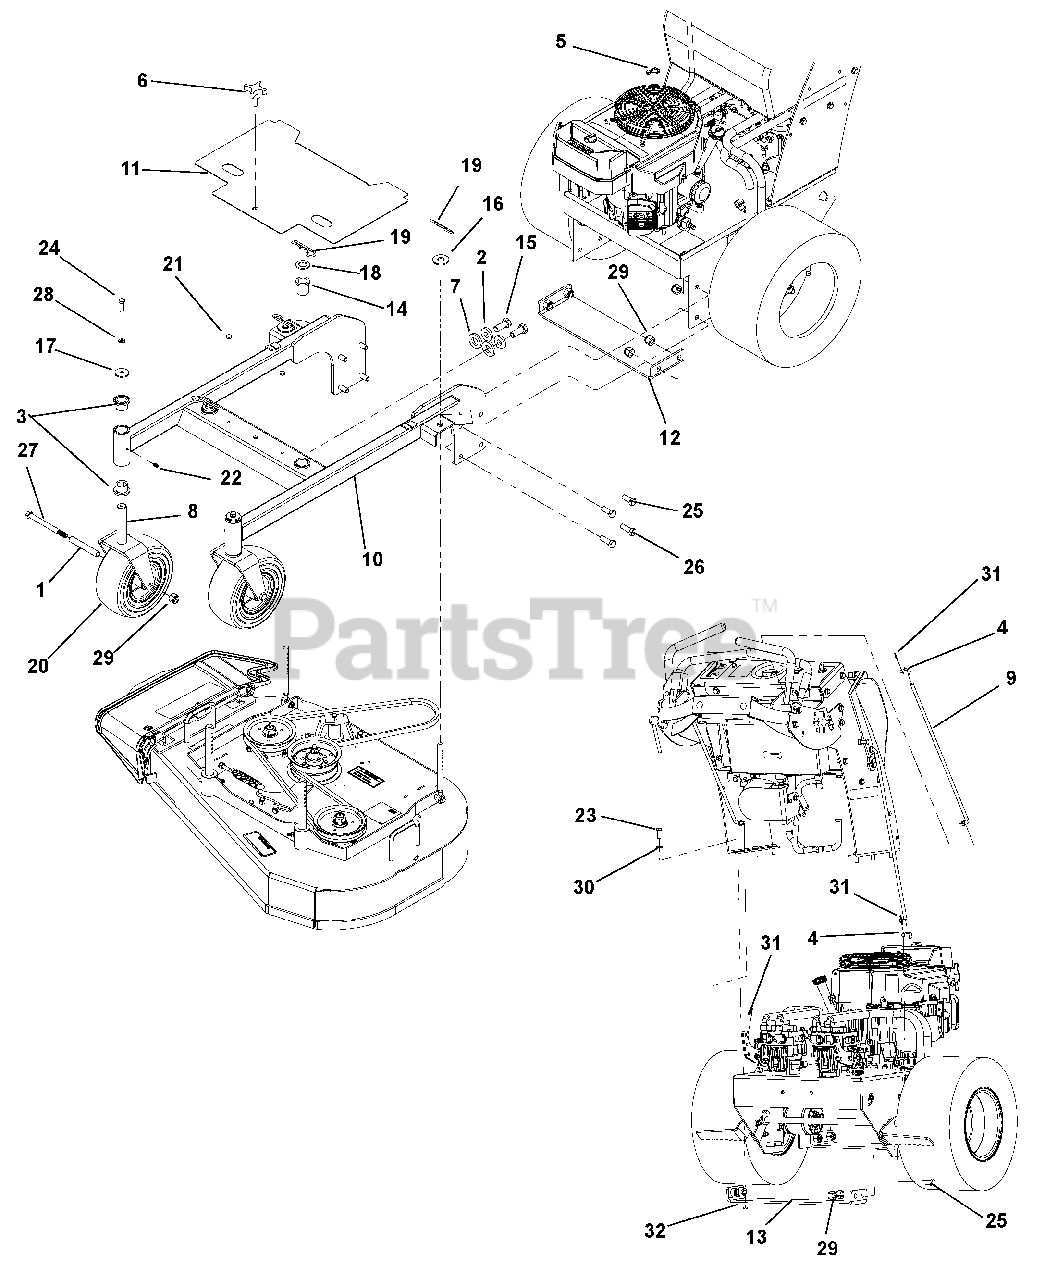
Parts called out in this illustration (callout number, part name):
1	TUBE, CASTER AXLE
2	WASHER, BLADE
3	BRG, FLG 1.00 X 1.25 X 1.00
4	SWIVEL, 3/8-24
5	CABLE TIE, .15 X 8.50
6	KNOB, 3/8 X 1.25 - 4 PRONG
7	WASHER, .905 X 1.750 X .250
8	WLDT, FRONT WHEEL FLOAT WALK
9	ROD, DRIVE CONTROL FW
10	WLDT, FRAME 36" FLWLK
11	SHIELD, BELT 36" FLOAT WALK
12	PLATE, ENGINE BED FRONT 36
13	PLATE, ENGINE BED REAR 36
14	BSHG-FLG 1.00X 1.25 X 1.50 X 1.50 EP REV
15	BOLT, 5/8-11 X 1.50 HEX 8 Y
16	WASHER, FLAT-STEEL .688 X 1.75 X.134 REV
17	WSH, FL-ST .38 X 1.50 X .125 REV
18	WASHER, FL-STL REV
19	PIN, HAIR INTERNAL .17 X .68 X 3.50 REV B
20	ASSY, WHEEL & TIRE - 9 X 3.5-4
21	BUMPER GROMMET .125 X .25 REV
22	FTG, 1/4-28 STRGT GREASE ZERK
23	BOLT, 3/8-16 X 1.00 HEX 5 Y
24	BOLT, 3/8-16 X 1.25 HEX 5 Y
25	BOLT, 1/2-13 X 1.25 HEX 5 Y
26	BOLT, 1/2-13 X 1.50 HEX 5 Y
27	BOLT, 1/2-13 X 5.50 HEX 5 Y
28	WASHER, .375 MED SPRG LOCK Y
29	LOCKNUT, 1/2-13 NYLOC Y
30	WASHER, .406 X .813 X .065 FLAT Y
31	RING, RUE .375 X .054 x 1.254
32	LOCKNUT, 3/8-16 NYLOC Y
